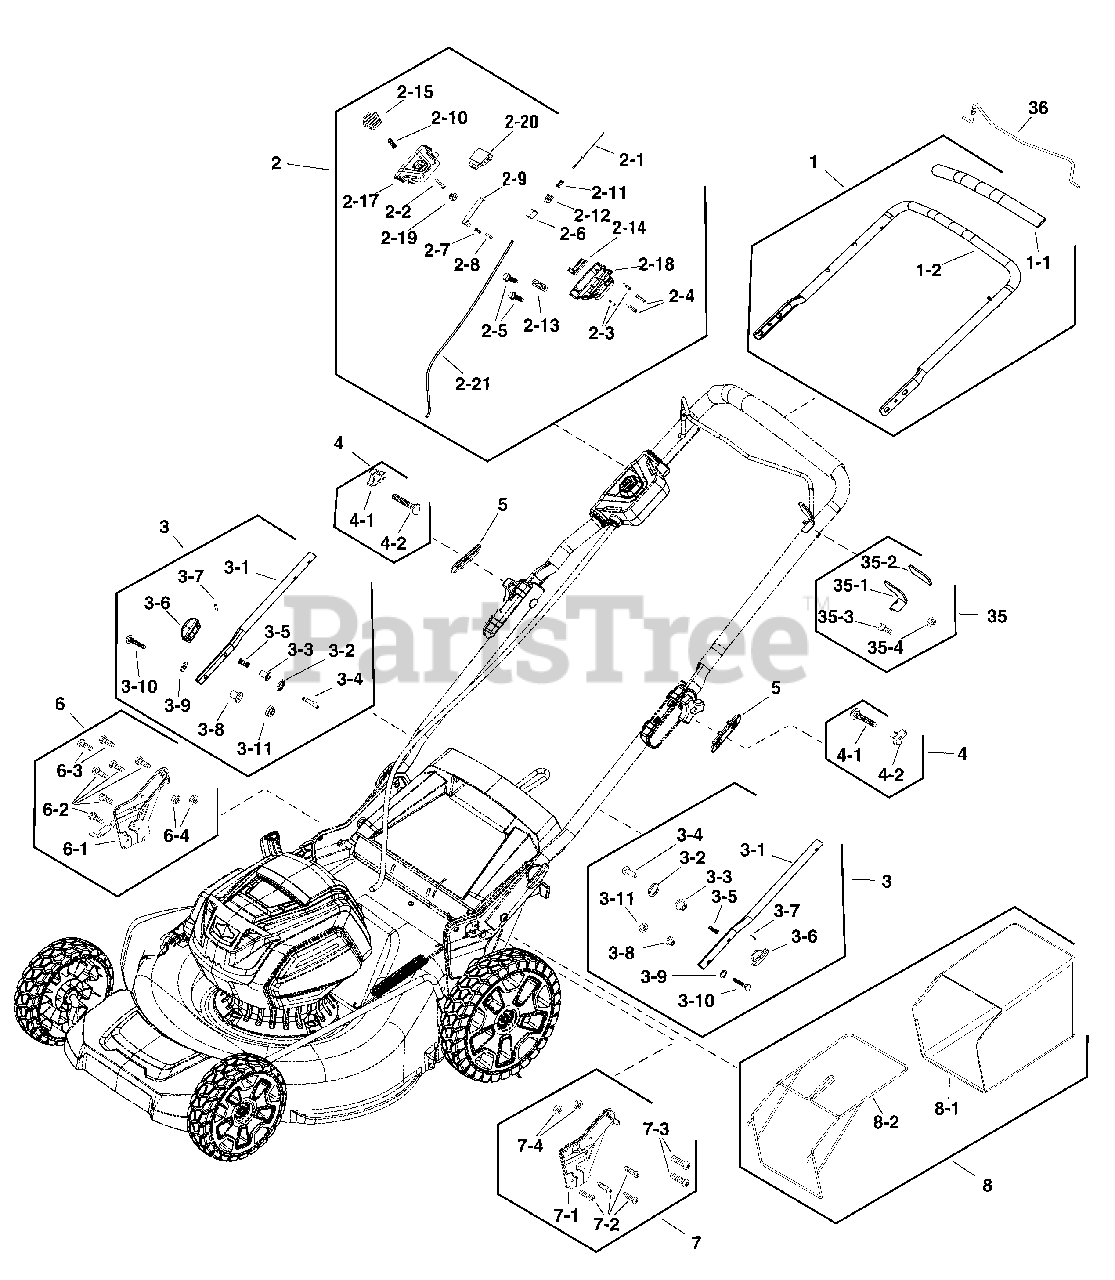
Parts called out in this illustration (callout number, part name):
1	KIT, UPPER HANDLE, NA
1-1	SPONGE
1-2	HANDLE, Upper
2	KIT, SWITCH BOX COMPONENT, NA
2-1	CABLE, Bail
2-6	SLIDER
2-7	PIN
2-8	SPRING
2-9	PLATE
2-10	SPRING
2-11	SPRING
2-12	SEAT
2-13	CLAMP
2-14	SLIDER
2-15	BUTTON, Start
2-17	SWITCH BOX COVER
2-18	SWITCH BOX COVER
2-19	COVER
2-21	HARNESS
3	KIT, Lower Handle
3-1	LOWER HANDLE
3-2	GASKET
3-3	INSERT
3-4	POST
3-5	SPRING
3-6	KNOB
3-7	PIN
3-8	BLOCK
3-9	WASHER, Flat
3-10	BOLT
3-11	NUT
4	KIT, HARDWARE
4-2	BOLT
5	KIT, SLEEVE
6	KIT, RIGHT BRACKET
6-1	BRACKET, Height Adjust
6-3	BOLT
6-4	NUT
7	KIT, LEFT BRACKET
7-1	HEIGHT ADJUST, LEFT
7-3	BOLT
7-4	NUT
8	KIT, GRASS BAGGER
8-1	BAG, Grass Catcher
8-2	FRAME
35	KIT, STOP
35-1	STOP
35-2	SPONGE
35-3	BOLT
35-4	NUT
36	KIT, LEVER
